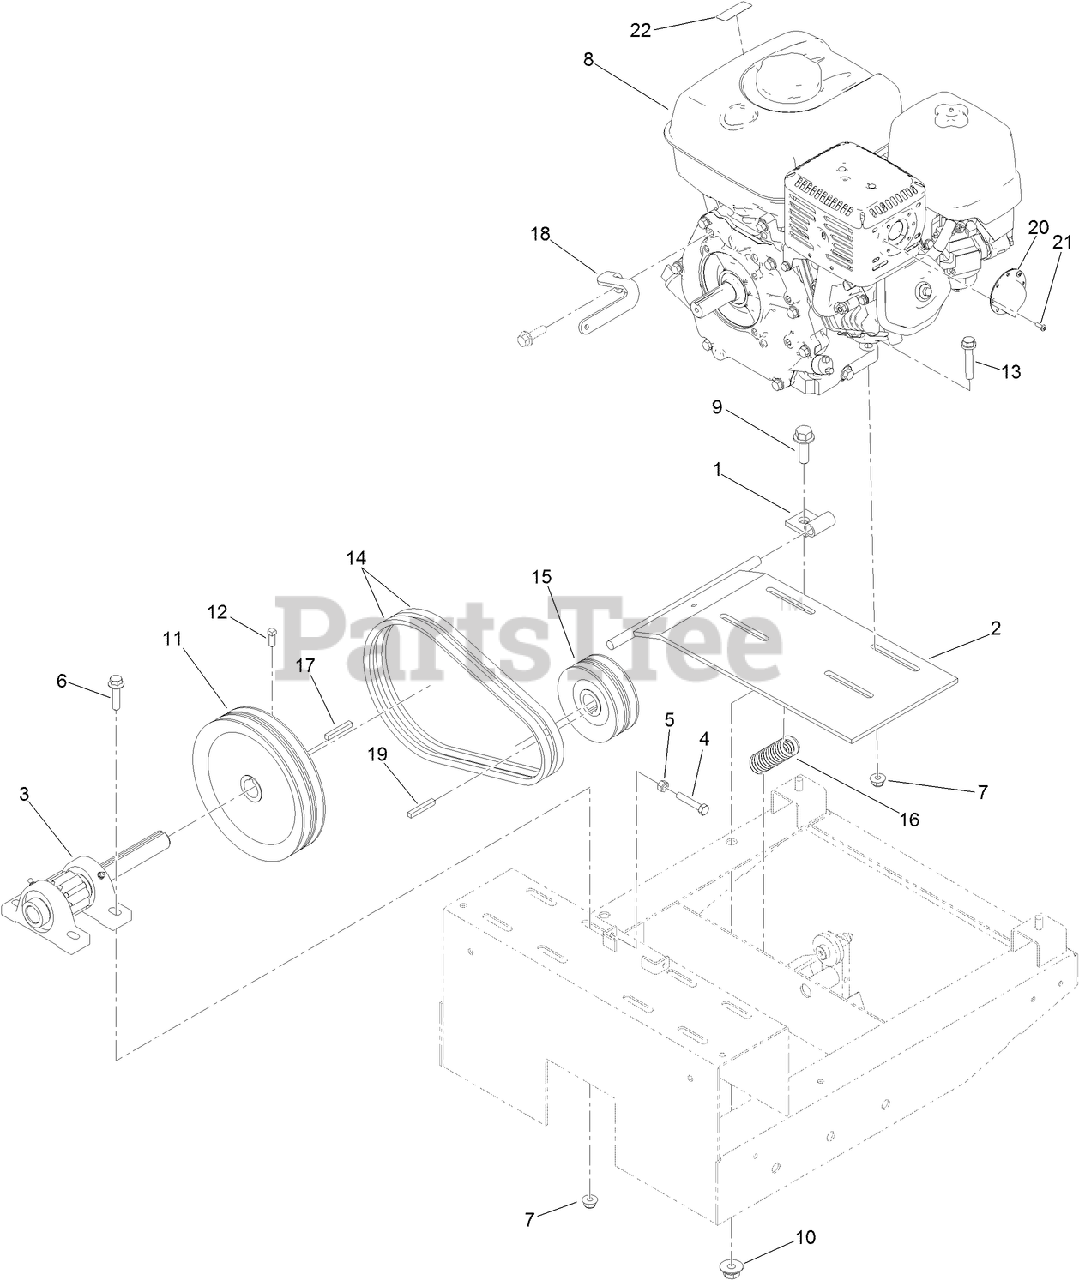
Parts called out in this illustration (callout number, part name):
1	MOUNT-MOTOR
2	BASE-MOTOR
3	PINION ASM
4	SCREW-HH
5	NUT-HEX
6	SCREW-HHF
7	NUT-HF, NI
8	ENGINE-HONDA, GX240
9	SCREW-HHF
10	NUT-HF
11	SHEAVE
12	SCREW-SET, SQH
13	SCREW-HHF
14	BELT-V
15	SHEAVE
16	SPRING
17	KEY-SQUARE
18	GUIDE-BELT
19	KEY-SQUARE
20	DEFLECTOR-EXHAUST
21	SCREW-TAP
22	DECAL-WARNING, ETHANOL
